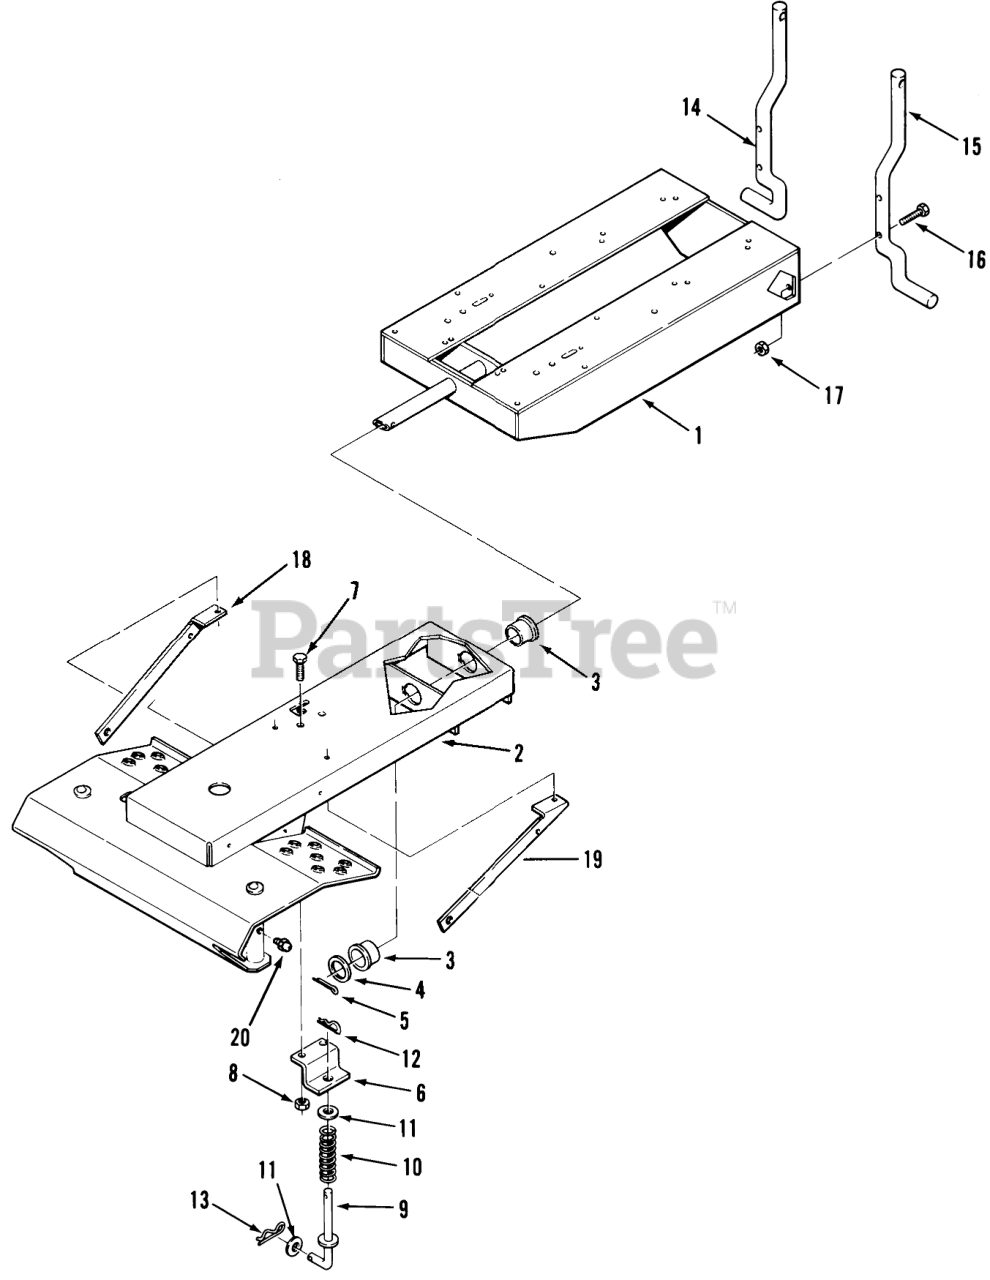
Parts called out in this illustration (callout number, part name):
1	Rear Frame Assy
2	Front Frame Assy
3	BEARING FLANGE
4	WASHER
5	Pin-Cotter
6	BRACKET R
7	Bolt
8	NUT
9	ROD ASSY R
10	SPRING-COMPRESSION
11	Washer
12	Hairpin Cotter
13	Hairpin
14	REAR ROD RH B
15	REAR ROD LH B
16	BOLT 5/16-18X1 1/2
17	Nut
18	ASSY BRACE AXLE LH
19	ASSY BRACE AXLE RH
20	Grease Zerk
